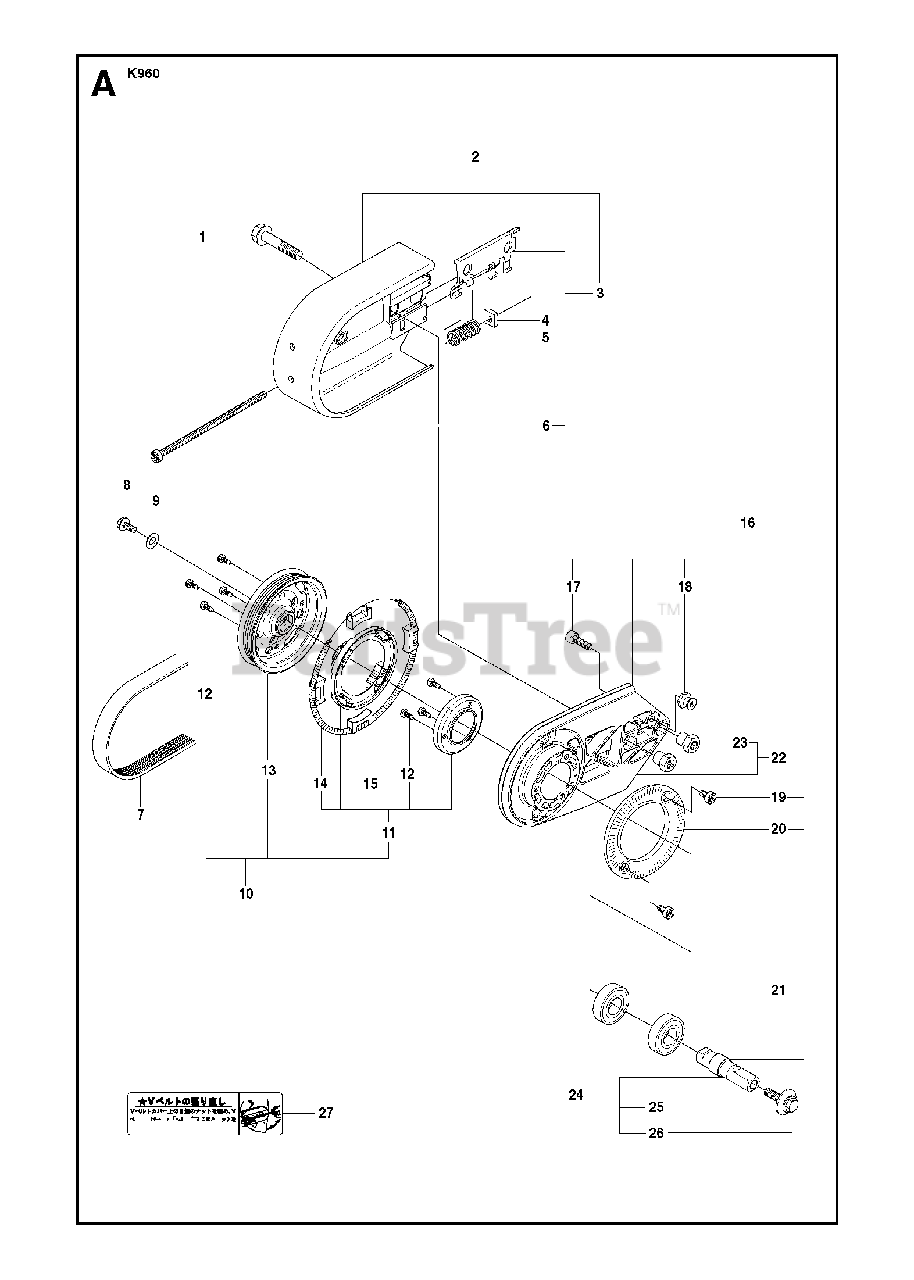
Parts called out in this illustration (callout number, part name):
2	BELT GUARDIncl. 3
3	BELT TENSIONER ASSYIncl. 4, 5, 6
5	COMPRESSION SPRING
6	SCREW CITXSCM
7	BELT"12"", 14"""
10	PULLEYIncl. 11, 12, 13
11	CASSETTEIncl. 12, 14, 15
12	SCREW CCRPANT
13	PULLEY
16	BEARING HOUSINGIncl. 17 - 21
17	SCREW ITXSCM
18	TORSION STOP
19	SCREW ITXSCM
21	BALL BEARING
22	BEARING HOUSINGIncl. 23
24	SHAFTIncl. 25, 26
